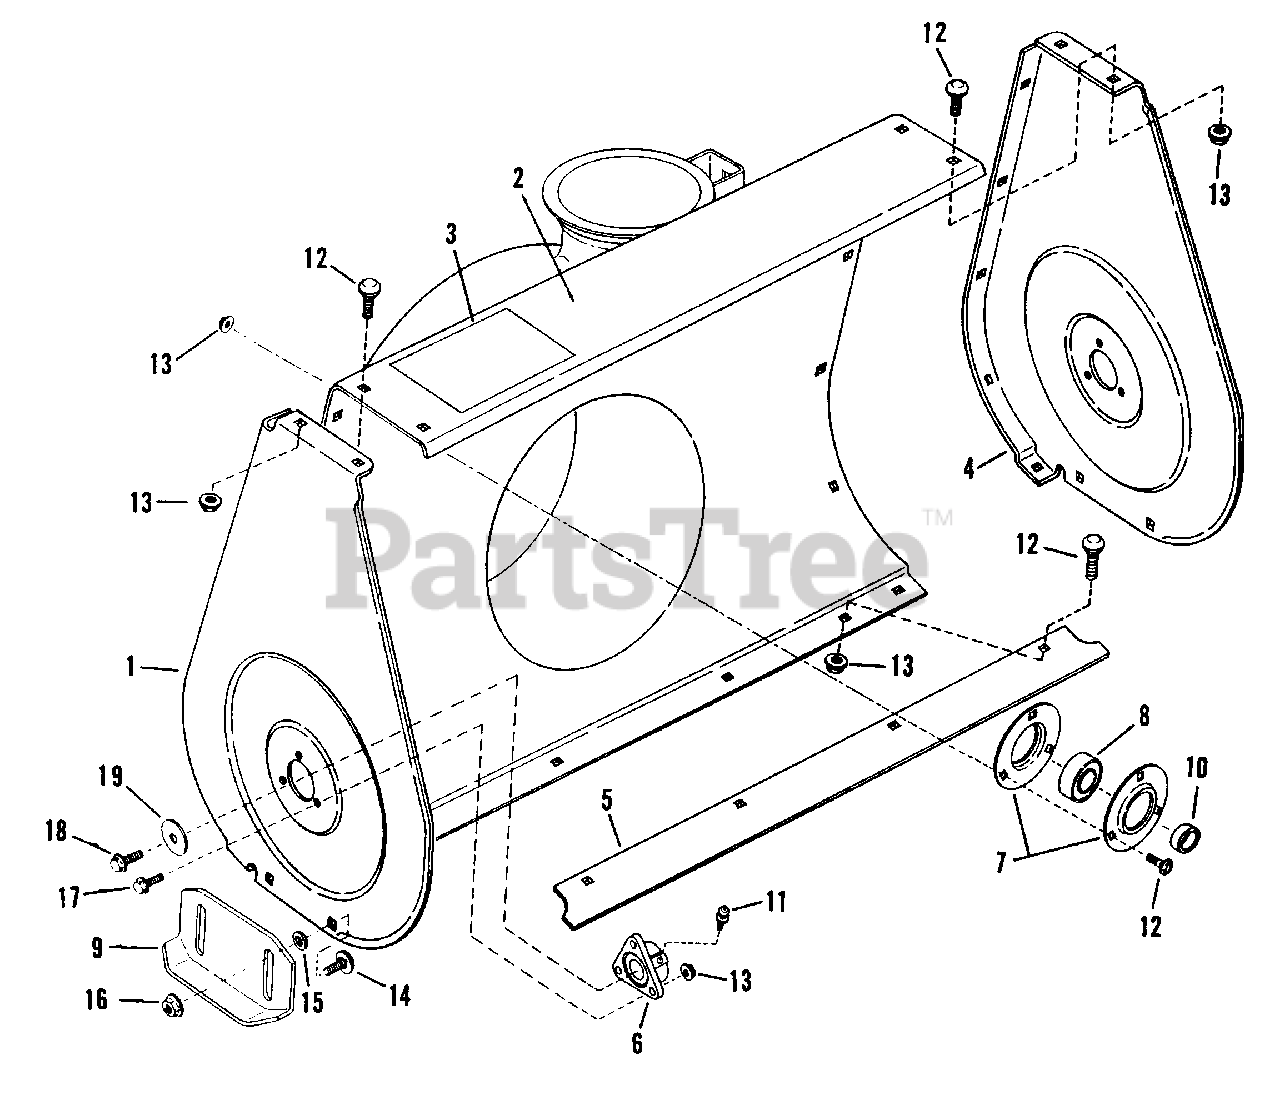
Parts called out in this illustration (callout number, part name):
1	PLATE, Right Hand Side
2	ASSEMBLY, Blower Housing
3	DECAL, Foot Danger
4	PLATE, Left Hand Side
5	BLADE, Scraper
6	BEARING, Auger Shaft
7	HOUSING, Bearing
8	BEARING, Ball
9	SKID-SHOE
10	SPACER (.76 x 1.0 x .25)
11	FITTING, Lube (Press fit for .187 hole-no ball)
12	BOLT, 1/4 - 20 x 5/8 S.N. Carriage
13	NUT, 1/4 - 20 x H. Flange Lock
14	BOLT, 5/16 - 18 x 5/8 Carriage
15	WASHER, 5/16 Flat
16	NUT, 5/16 - 18 H. Flange Lock
17	BOLT, 1/4 - 20 x 3/4 H. Flange ZLock
18	SCREW, 5/16 - 18 x 5/8 Self-Tapping
19	WASHER, Flat
